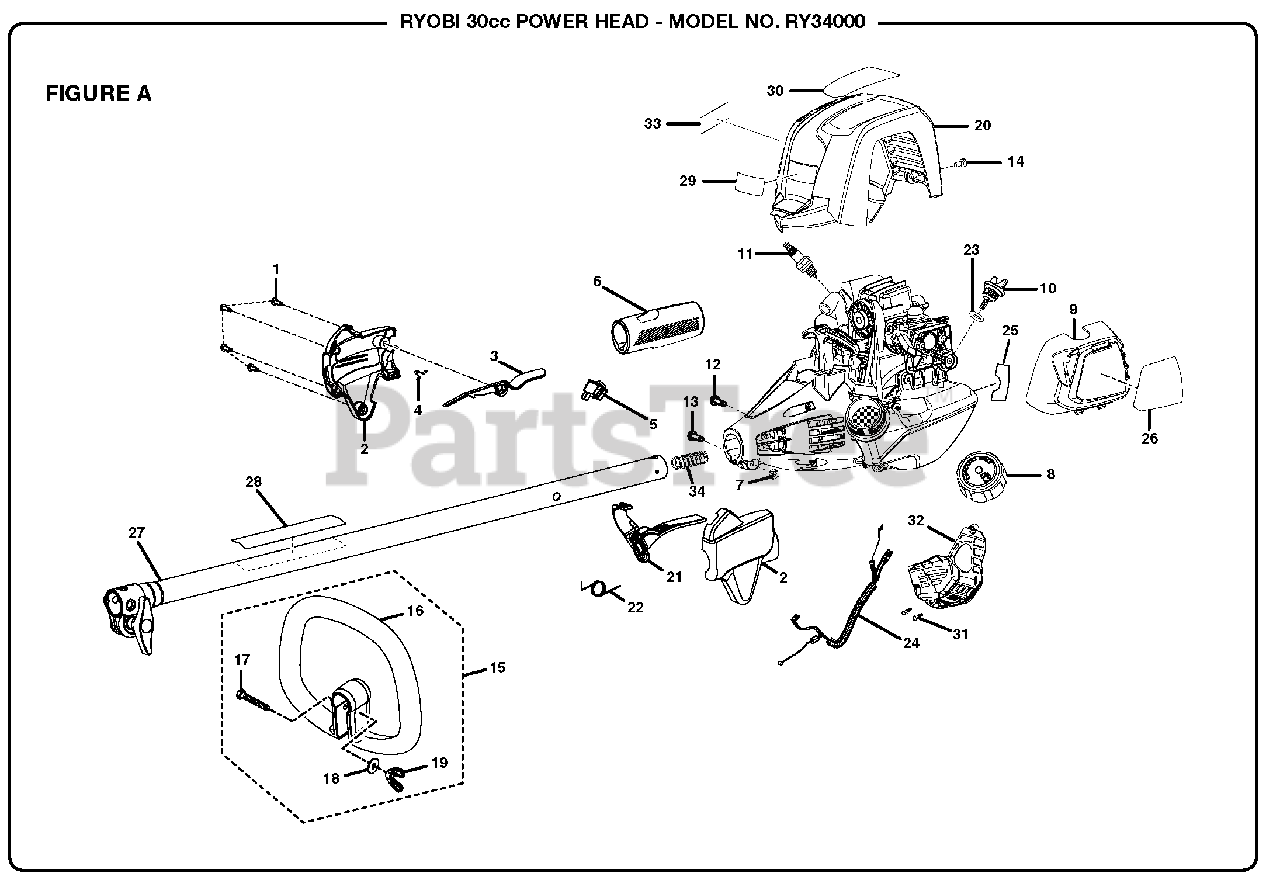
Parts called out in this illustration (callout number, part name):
1	Screw (M4 x 20 mm)
2	Control Handle Assembly
3	Trigger Lock
4	Strap Hanger
5	Switch (Momentary Contact)
6	Rear Handle
7	Hex Nut (M6.3 x 1)
8	Fuel Cap Assembly
9	Air Box Cover
10	Oil Cap/Dipstick
11	Spark Plug (Champion RY4C)
12	Screw (#8-16 x 5/16 in., Torx TF)
13	Bolt (M6 x 20 mm)
14	Screw (M5 x 11 mm)
15	Front Handle Assembly
16	Front Handle
17	Bolt (1/4-20 x 40 mm)
18	Washer (1/4 in.)
19	Wing Nut (1/4-20)
20	Top Cover Assembly
21	Throttle Trigger
22	Throttle Trigger Spring
24	Throttle Cable and Lead Assembly
25	Hot Surface Label
26	Starting Label
27	Upper Boom Assembly
28	Warning Label
29	Logo Label
30	X430 Label
31	Screw (#6-19 x 1/2 in.)
32	CE Cover (Bottom Cover)
33	Combustion Warning Label
34	Compression Spring
